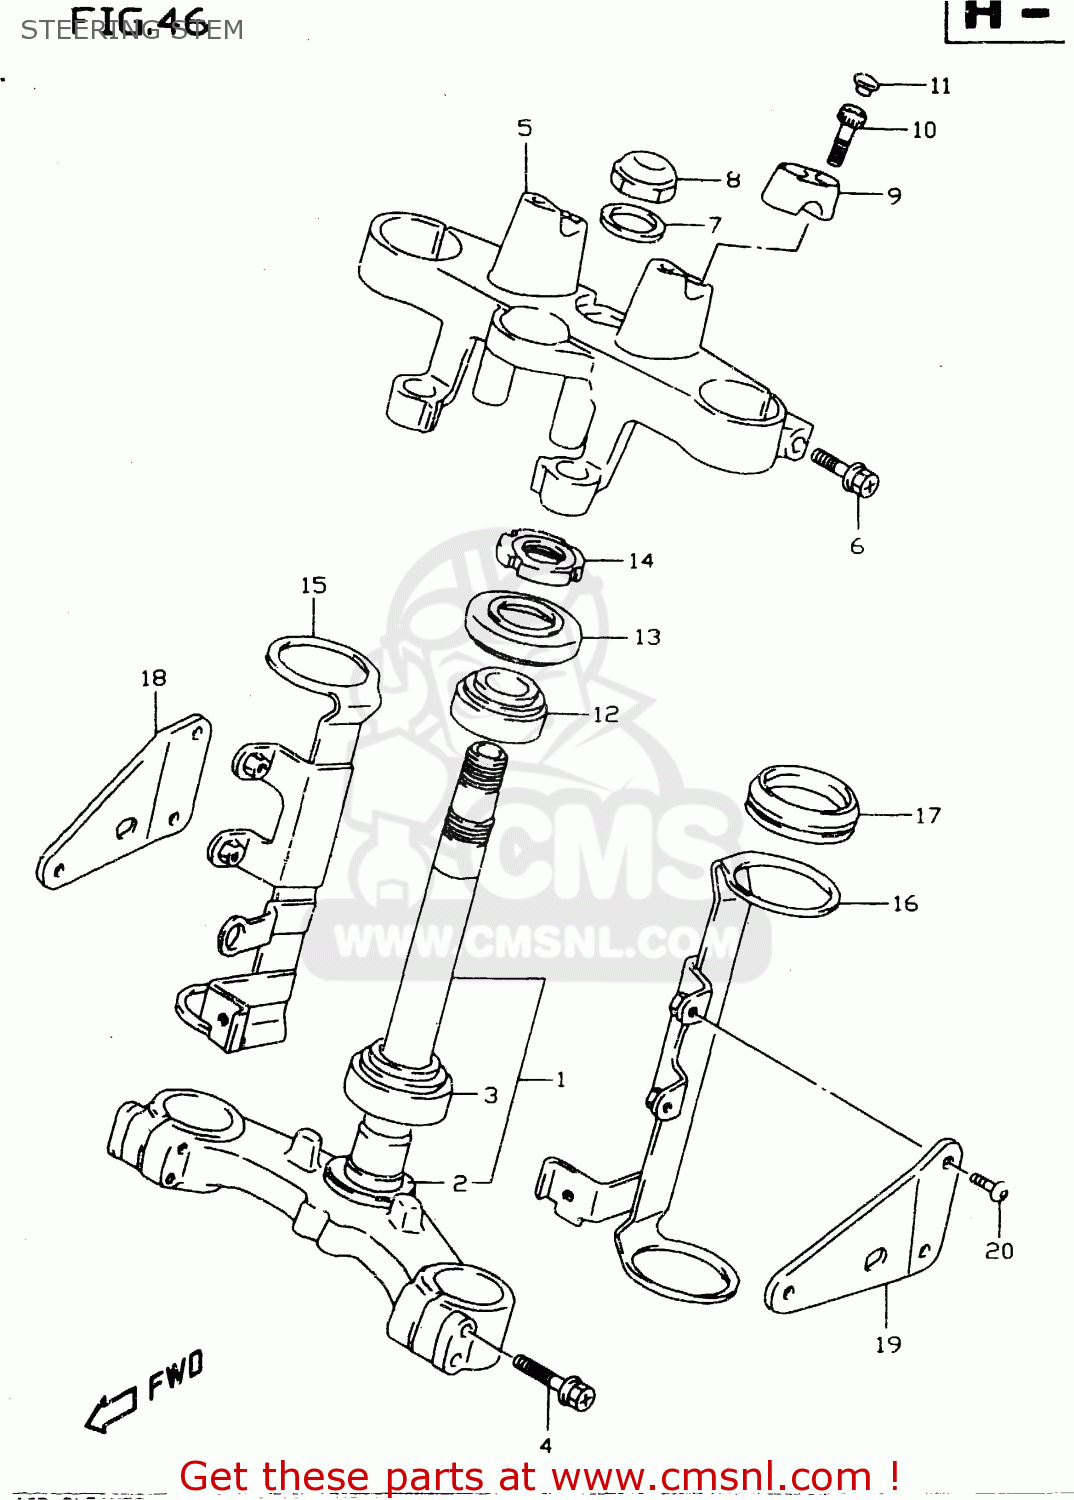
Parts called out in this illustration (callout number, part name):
1	STEM,STEERING
2	SEAL,STEERING LWR
3	BEARING(30X55X17)
4	BOLT
5	HEAD,STEERING STEM
6	BOLT
7	WASHER(22.5X32X1.6)
8	NUT
9	HOLDER,HANDLE
10	BOLT
11	CAP(OD:11)
12	BEARING(25X47X15)
13	DUST SEAL,STEERING UPR
14	NUT,STEERING STEM(25X44X10)
15	BRACKET,HEADLAMP HOUSING,R
16	BRACKET,HEADLAMP HOUSING,L
17	DAMPER,HEADLAMP HSG BRACKET
18	STAY,HEADLAMP HOUSING,R
19	STAY,HEADLAMP HOUSING,L
20	SCREW(6X12)
